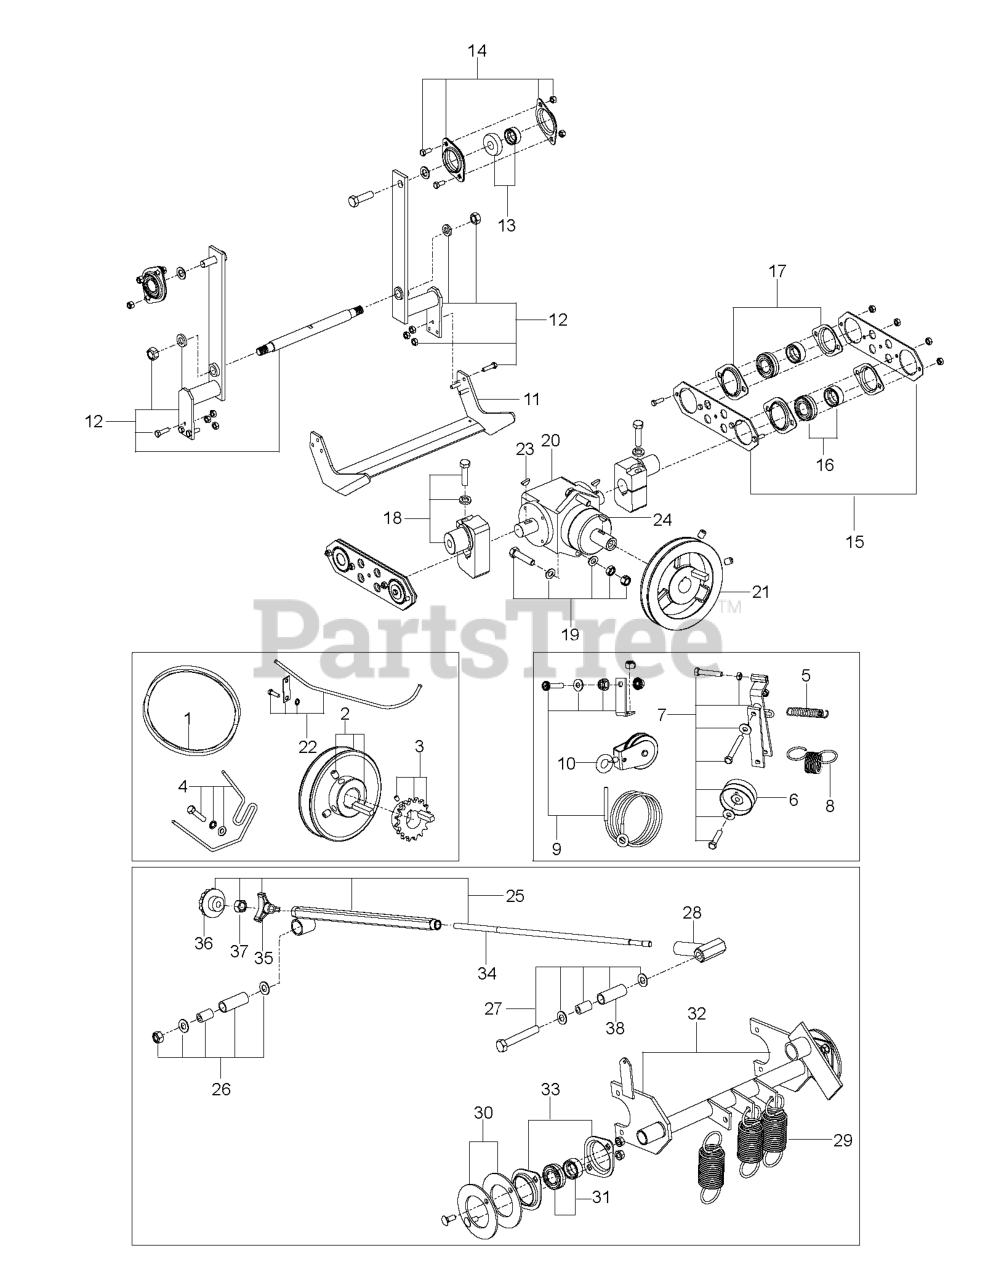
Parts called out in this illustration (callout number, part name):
1	V-BELT
2	V-PULLEY
3	SPROCKET
4	BELT KEEPER WITH HARDWARE
5	SPRING, IDLER CAM, 3 3/4"
6	PULLEY
7	ARM, IDLER ASSEMBLY
8	SPRING
9	CABLE
10	PULLEY
11	KIT, BLADE, 18" STD
12	SHAFT SET - SOD CUTTER
13	BEARING
14	STAMPING KIT
15	PLATE, ROD
16	BEARING 1"
17	STAMPING KIT
18	CRANK
19	HARDWARE KIT
20	GEAR BOX
21	PULLEY
22	TUBE, THRTLE CABLE
23	KEY, #6 WOODRUFF
24	KEY, #9 WOODRUFF (3/16 X 3/4)
25	DEPTH ADJUSTER ASM HV GRAY
26	FASTENER KIT
27	FASTENER KIT
28	ROD END
29	SPRING
30	SPACER
31	BEARING 1"
32	TRUNNION ASSEMBLY
33	STAMPING KIT
34	DEPTH ADJUST SCREW
35	KNOB, THREE PRONG(DEPTH LOCK)
36	KNOB, DEPTH
37	NUT, HEX, JAM 1/2-13 UNC
38	BUSHING
